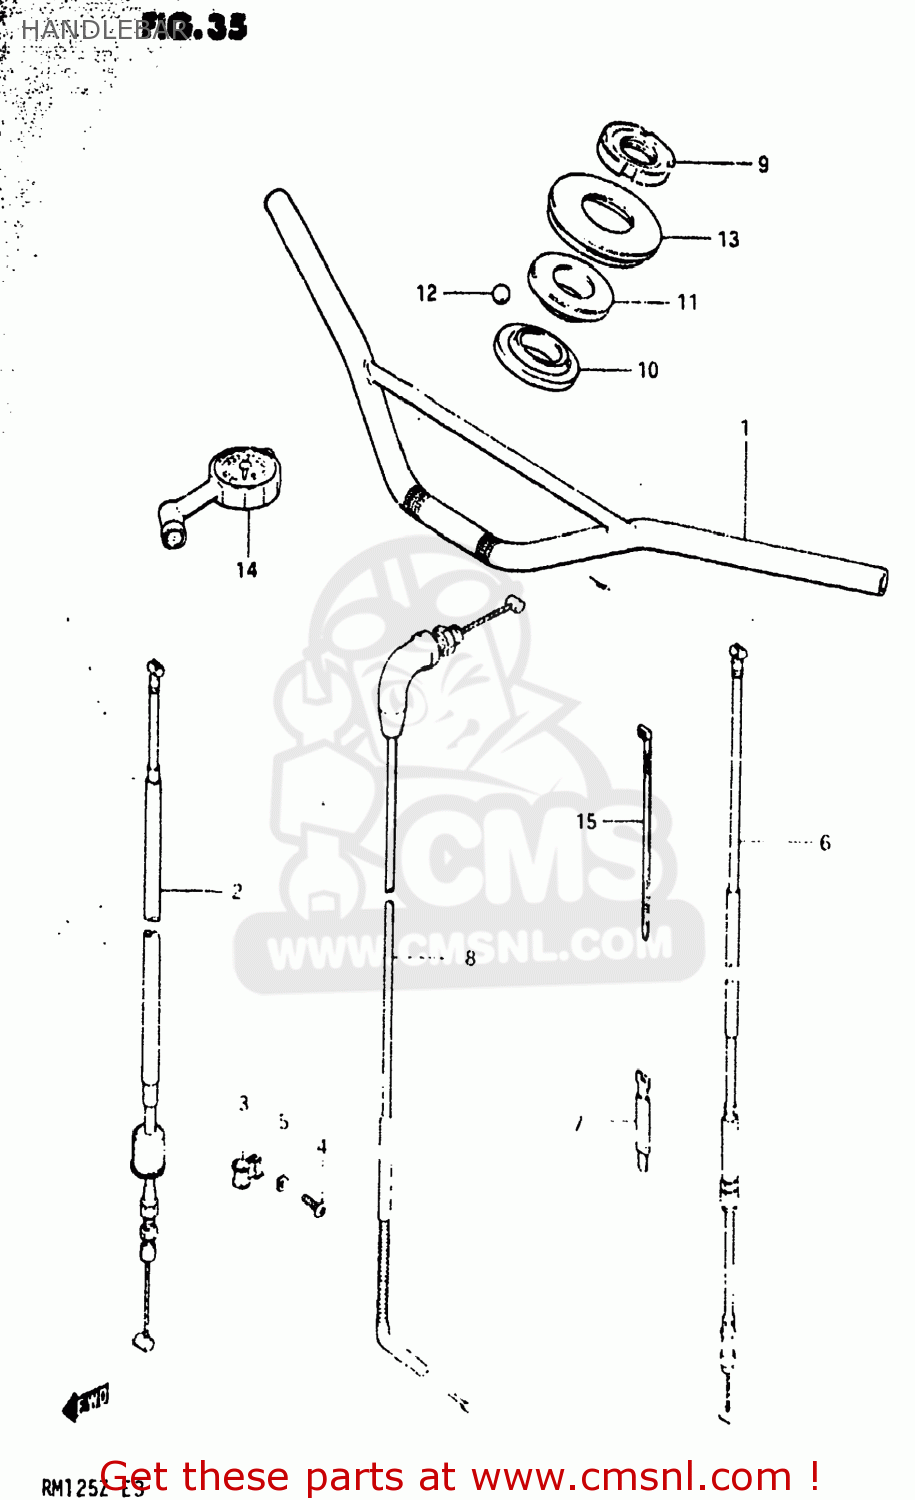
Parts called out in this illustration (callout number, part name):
1	HANDLEBAR
2	HANDLEBAR
3	GUIDE,CABLE
4	SCREW
5	LOCK WASHER
6	CABLE ASSEMBLY,CLUTCH
7	CLAMP
8	CABLE ASSEMBLY,THROTTLE
9	NUT,STEERING STEM
10	RACE,STEERING,INNER,UPPER
11	RACE,STEERING,OUTER,UPPER
12	BALL
13	SEAL,STEERING UPR DUST
14	GAUGE ASSY,AIR PRESSURE
15	CLAMP
